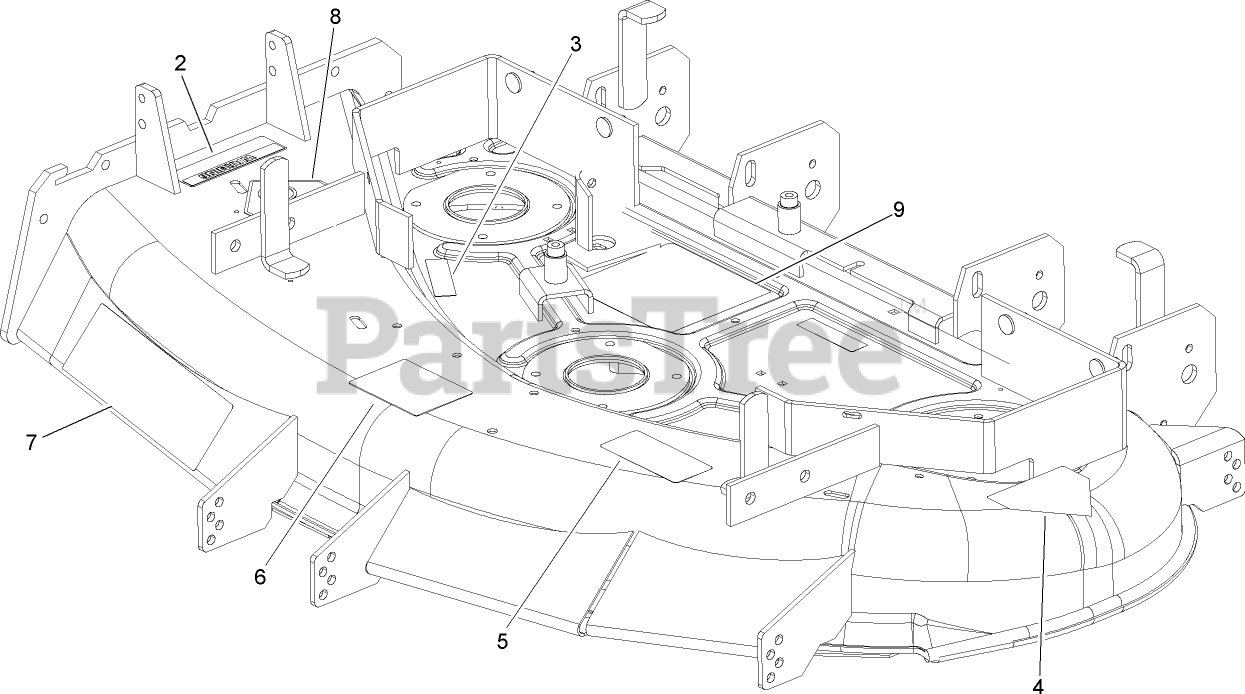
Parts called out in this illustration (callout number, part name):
2	DECAL-WARNING
3	DECAL-COVER, MISSING
4	DECAL-DANGER
5	DECAL-TORQUE
6	DECAL-WHEEL, GAGE
8	DECAL-DANGER
9	DECAL-SERVICE AID, BELT ROUTING
